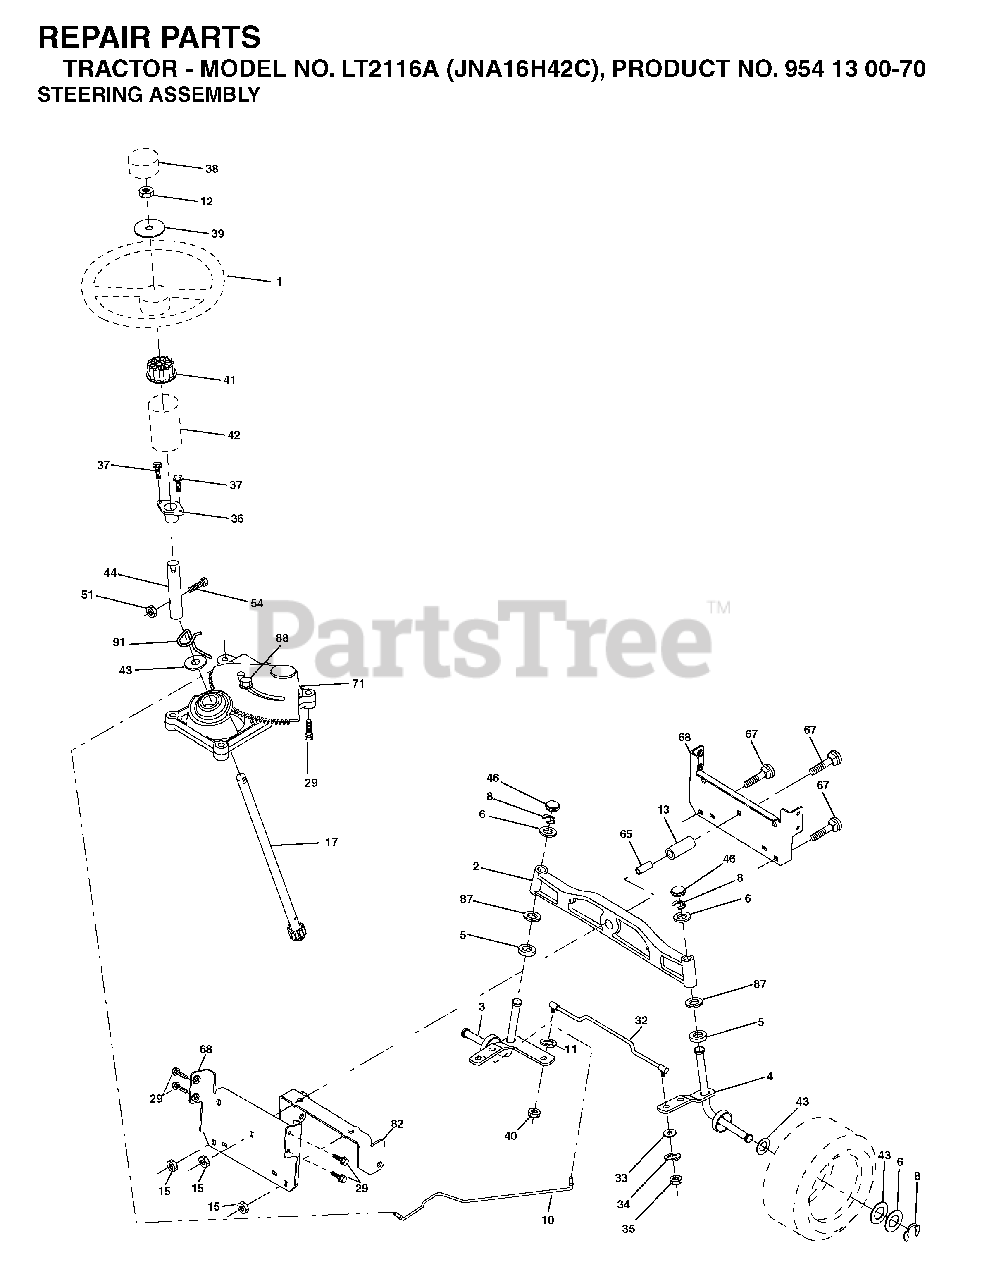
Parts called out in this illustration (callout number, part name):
2	AXLE ASSY FRONT
3	SPINDLE.ASM.LH.15"TIRES
4	SPINDLE.ASM.RH.15"TIRES
8	RING CLIP
10	DRAGLINK.15".TIRES.2001
11	WASHER, LOCK 3/8
12	NUT.HEX.1/2-20
13	TUBE, PIVOT AXLE
15	NUT
17	SHAFT ASM, STEERING
29	SCREW 3/8-16X3/4
33	WASHER M
34	LOCKWASHER
35	NUT, CROWNLOCK
36	BUSHING, STEERING
40	GRIPCO NUT
41	STEERING WHEEL ADAPTOR
42	BOOT.STEERING.SHAFT.BLACK
44	EXT, STEERING SHAFT
46	CAP.SPINDLE
51	CROWN LOCKNUT
65	SPACER BRACE AXLE
67	BOLT
68	BRACE.AXLE.15"TIRES
71	STEERING ASM
82	BRACKET
87	WASHER, FLAT .781 X 1 1/2"
88	BOLT, SHOULDER 7/16-20
91	CLIP.STEERING
